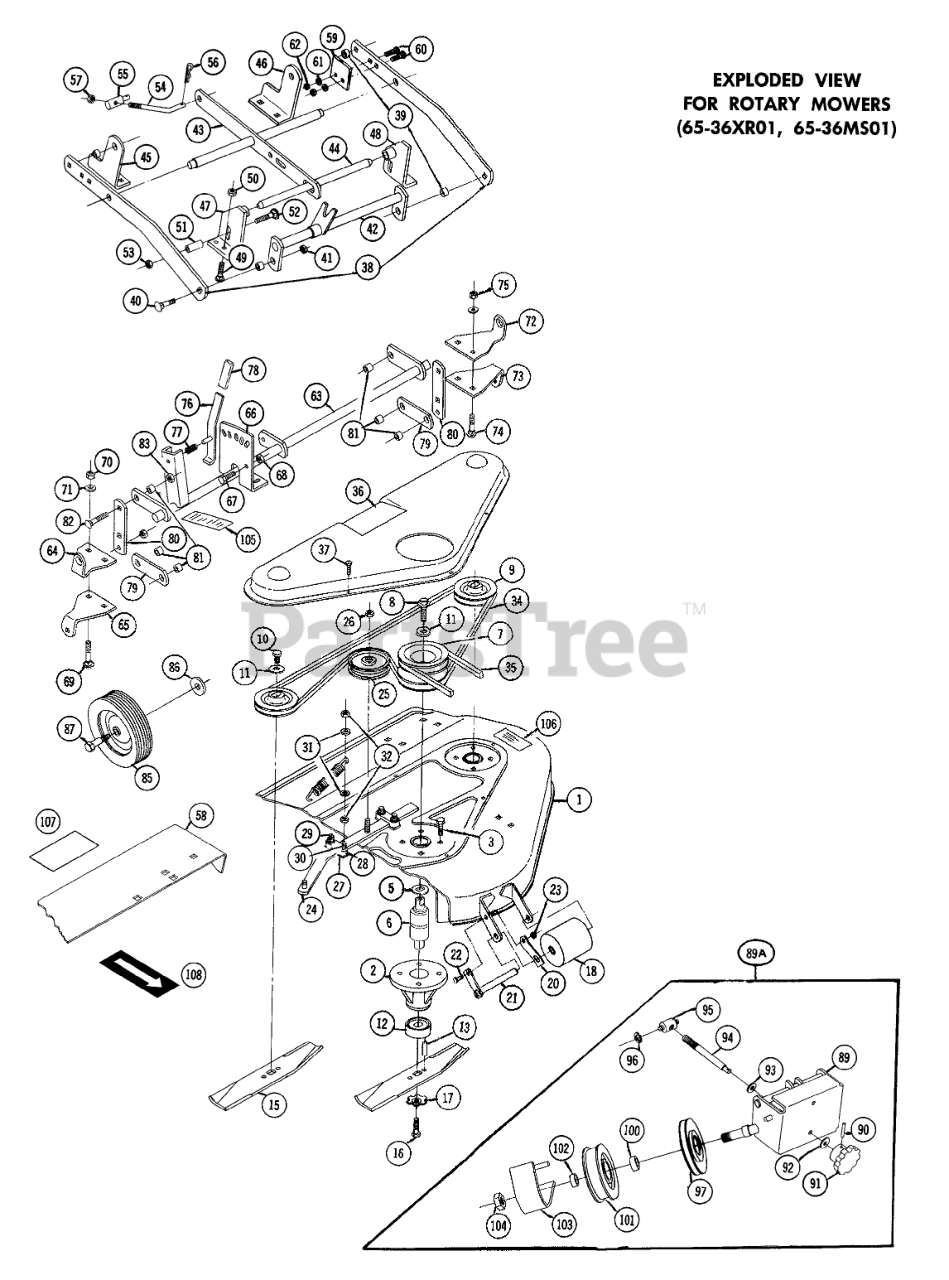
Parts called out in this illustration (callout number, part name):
1	Deck-Mower-Rear Discharge 5-0622)
1	Deck-Mower Side Discharge (5-0721)
2	HOUSING-BEARING B
3	Bolt
5	WASHER-DOUBLE D
6	BEARING
7	Pulley-Center Drive
8	Bolt-Lock 3/8-16 x 7/8
9	Pulley
10	Bolt
11	WASHER
12	Cup-Spindle
13	SPIROL ROLL PIN
15	BLADE KIT 36 LF REAR
15	BLADE KIT
16	Bolt
17	WASHER
18	Roller
20	SPRING ROLLER STOP
21	Roller Shaft
22	H H C S
23	Nut
24	Bar Idler Support
25	Idler Pulley
26	Nut
27	SLIDE
28	Side Block
29	Bolt-Carriage
30	Bolt-Carriage
31	WASHER 5/16 SAE
32	Nut
33	SPRING R
34	V-BELT
35	V-BELT
36	Belt Cover
37	Bolt
38	Bar Draft
39	SPACER
40	Bolt
41	LOCKNUT-FLANGE
42	Hitch
43	Leveler
44	Front Shaft
45	R.H. Rear Bracket
46	L.H. Rear Bracket
47	Front Bracket RH
48	Front Bracket LH
49	Bolt-Carriage
50	Nut
51	SPACER-BEARING
52	CARRIAGE BOLT -4
53	Nut
54	ROD-LEVEL ADJUST
55	TRUNNION-LIFT
56	Hairpin
57	NUT
58	Extension-Chute
59	BUMPER
60	Bolt-Carriage
61	Collar
62	Nut
63	Gage Wheel Support Assy.
64	Bracket-R.H. Upper
65	Bracket-Lower R.H.
66	Quadrant
67	Bolt
68	Nut
69	Bolt
70	Nut
71	Washer
72	Bracket-L.H. Upper
73	Bracket-L.H. Lower
74	Bolt
75	Nut
76	Lever
77	SPRING-COMPRESSION
79	SUPPORT LINK R
80	WHEEL SUPPORT LINK
81	SPACER
82	Bolt
83	LOCKNUT-FLANGE
85	Wheel
86	WASHER
87	BOLT-SHOULDER
88	Nut
89	Front Support
89A	ASM-SUPPORT,IDLER
90	PIN-ROLL
91	KNOB-ADJUSTMENT
92	Spring Washer
93	Washer
94	ROD ADJ
95	TRUNNION-DOUBLE
96	E Ring-3/8
97	Pulley-V
100	SPACER
101	PULLEY-FLAT IDLER
102	SPACER-OUTER
103	Belt Cover
104	Nut 3/4-16 MF
105	Decal Belt Diagram
106	Caution Decal
107	Guard Decal
108	Decal-Edge of Cut
109	S/A SPINDLE ASSY
